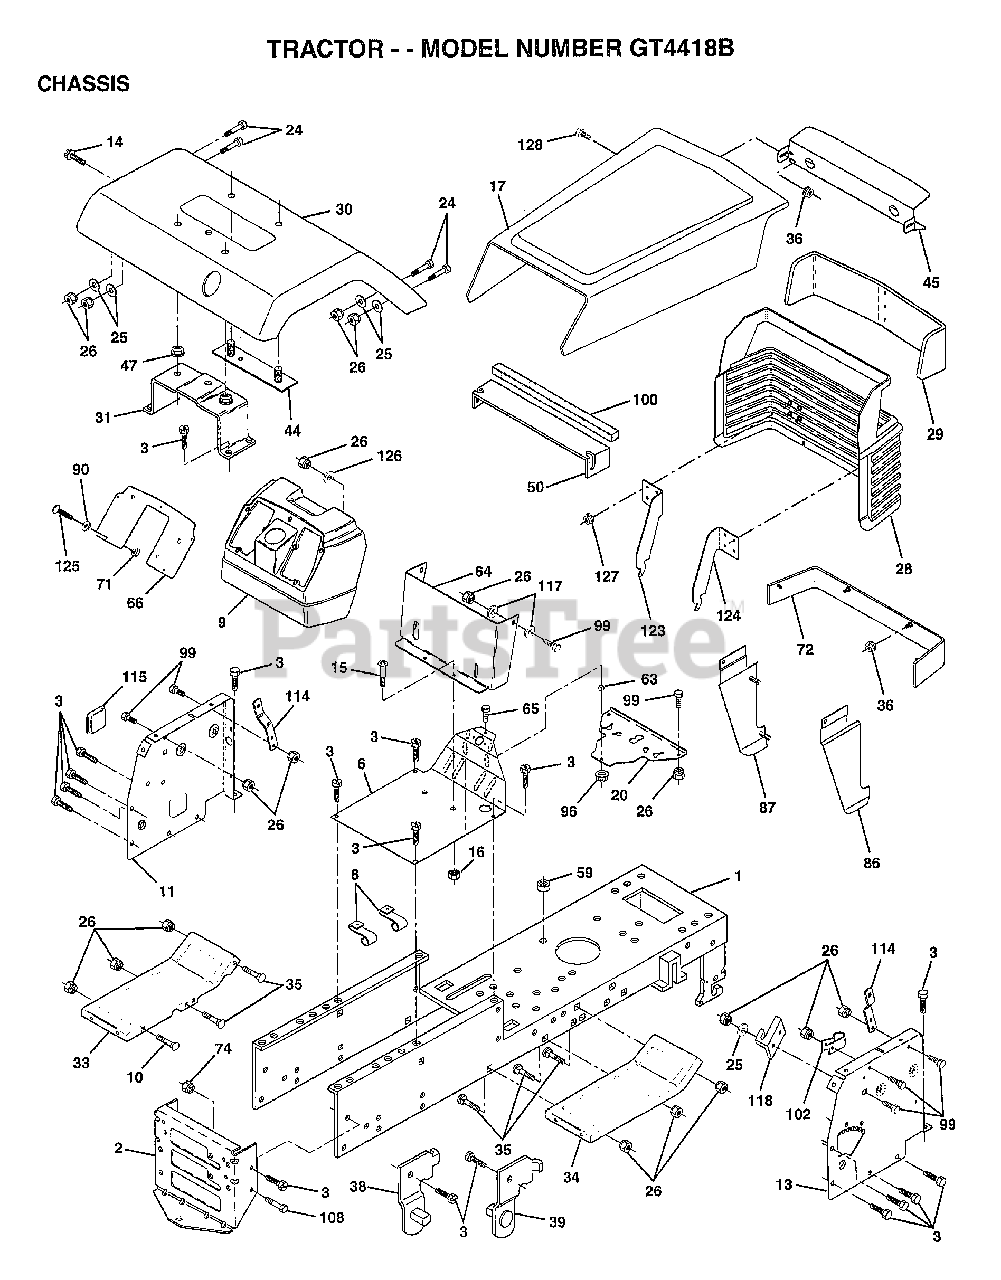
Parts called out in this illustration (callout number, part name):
2	DRAW BAR
3	SCREW
8	"CLIP,INSULATOR"
9	DASH.PLASTIC.BLK
11	PANEL.DASH.LH
13	PANEL.DASH.RH
14	SCREW LT
15	SCREW
17	HOOD/GRILLE ASM
20	PLATE.SUPT.BATTER
24	BOLT
25	WASHER
26	NUT
28	GRILLE ASM WELD
30	FENDER PNT
31	BRKT.ASM.FENDER
35	BOLT
36	PAL NUT LT
38	BRACKET ASM LH
39	BRACKET ASM RH
44	STRAP ASM FENDER
47	NUT-PUSH YT
50	"BAFFLE,HOOD"
63	SPACER
64	DASH-LOWER YT
65	BOLT
66	PLATE DASH SILKSC
71	NUT HXKEP 1/4X20
72	STRAP FENDER ASM
86	PANEL SIDE RH ASM
87	PANEL SIDE LH ASM
90	WASHER PM
96	NUT
99	BOLT
100	FOAM STRIP T
102	CLIP T
114	BRACKET.ASM.SUPT.
115	COVER ACCESS
117	WASHER.SERRATED.
124	BRACKET.PICK.RH
125	SCREW
126	WASHER
127	PAL NUT
128	SCREW SPECIAL
